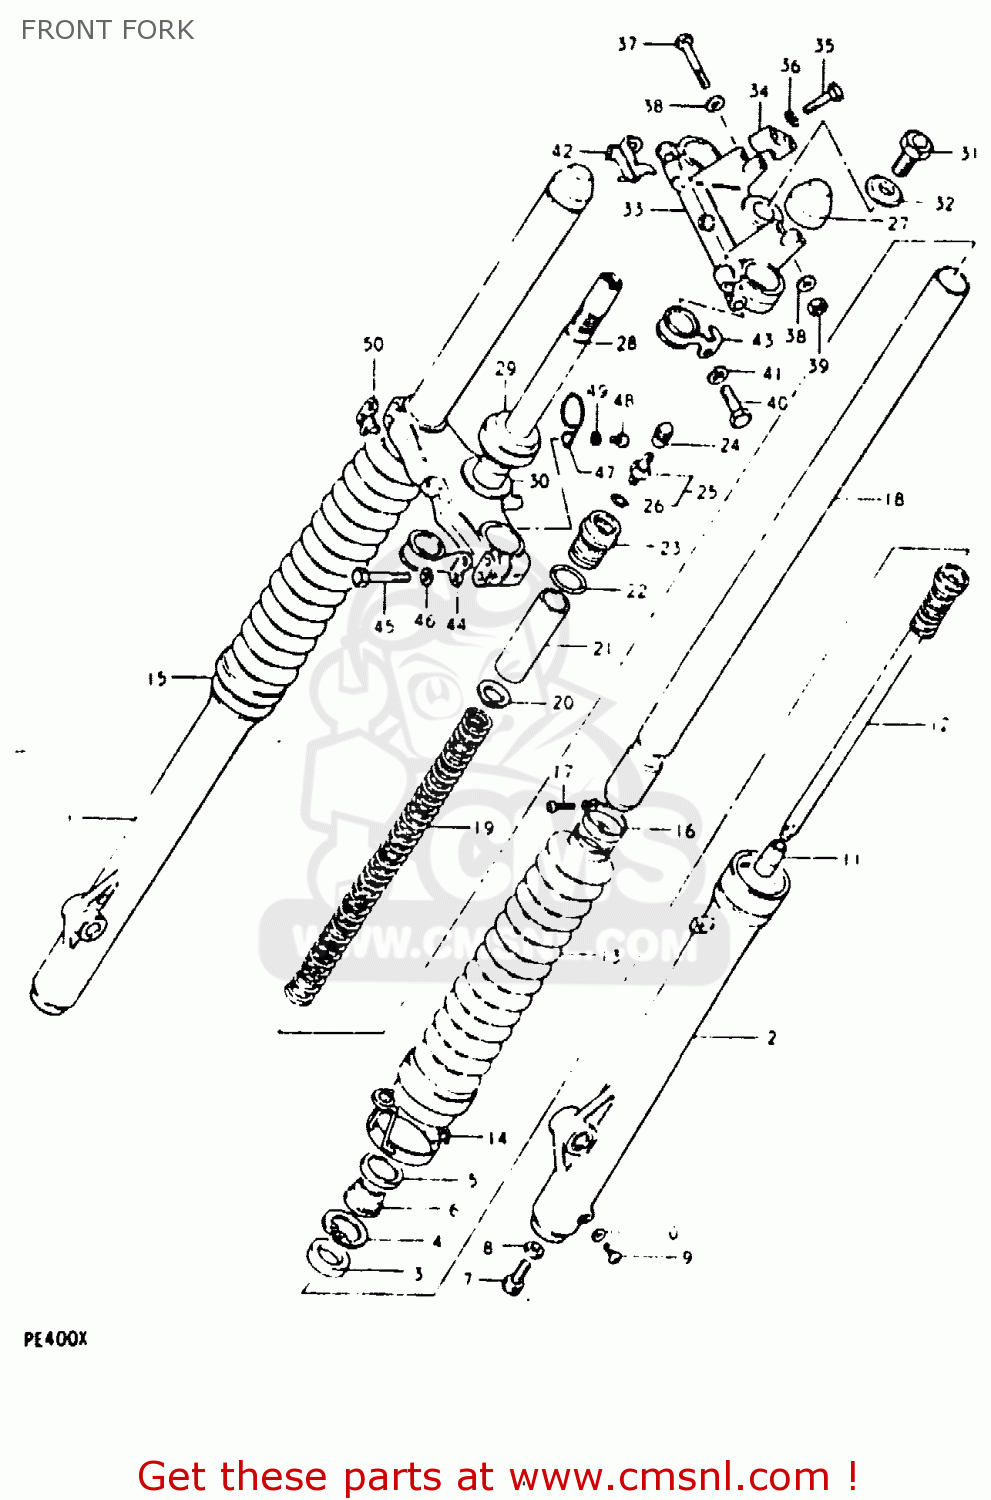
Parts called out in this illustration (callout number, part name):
1	TUBE,OUTER,RIGHT
2	TUBE,OUTER,LEFT
3	OIL SEAL,FRONT FORK
4	5
5	CASE,DUST SEAL
6	SEAL,DUST
7	BOLT,FORK CYLINDER(10X25)
8	GASKET (NAS)
9	SCREW
10	GASKET,DRAIN,PLUG (NAS)
11	PIECE,OIL LOCK
12	CYLINDER,FRONT FORK
13	BOOT
14	BAND,FORK COVER BOOT
15	BAND,FRONT FORK COVER
16	BAND,BOOT
17	SCREW
18	TUBE,FORK,INNER
19	SPRING
20	GUIDE,FRONT FORK SPRING C
21	COLLAR,SPRING
22	O RING
23	CAP,FORK INNER TUBE
24	CAP,VALVE
25	VALVE
26	O RING
27	CAP
28	STEM,STEERING
29	BEARING
30	WASHER,THRUST
31	BOLT
32	WASHER
33	HEAD,STEERING STEM
34	HOLDER,HANDLEBAR
35	BOLT
36	LOCK WASHER
37	BOLT 8X50
38	WASHER
39	NUT
40	BOLT
41	LOCK WASHER
42	BRACKET,TOOL FITTING,UPPER
43	GUIDE,CABLE
44	CLIP,CABLE
45	BOLT 8X45
46	LOCK WASHER
47	CLIP
48	SCREW
49	LOCK WASHER
50	BRACKET,TOOL FITTING,LOWER
